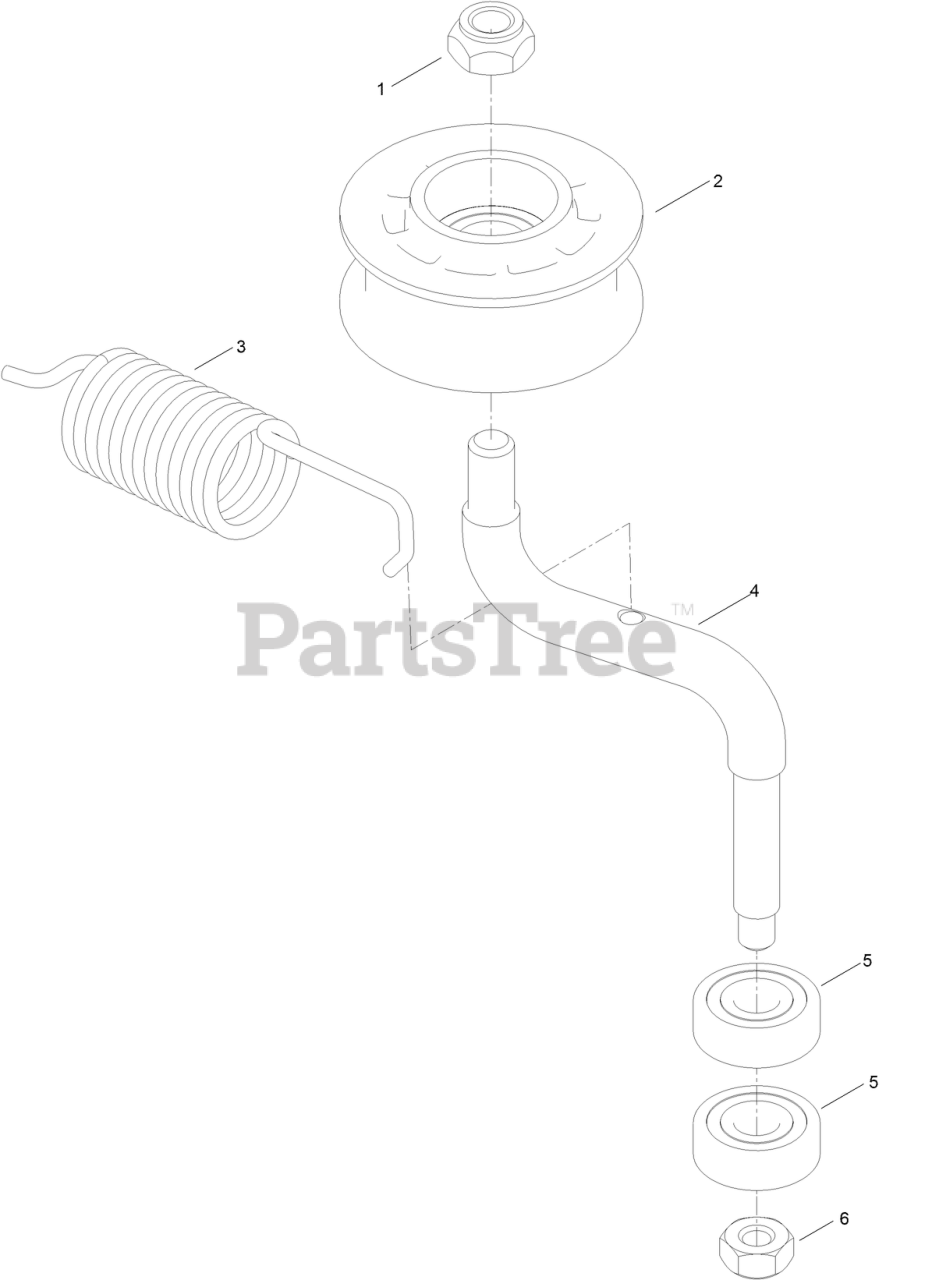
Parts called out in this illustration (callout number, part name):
1	NUT-M8
2	PULLEY-IDLER
3	SPRING-TENSION, BELT
4	ARM-IDLER
5	BEARING
6	NUT-HEX
